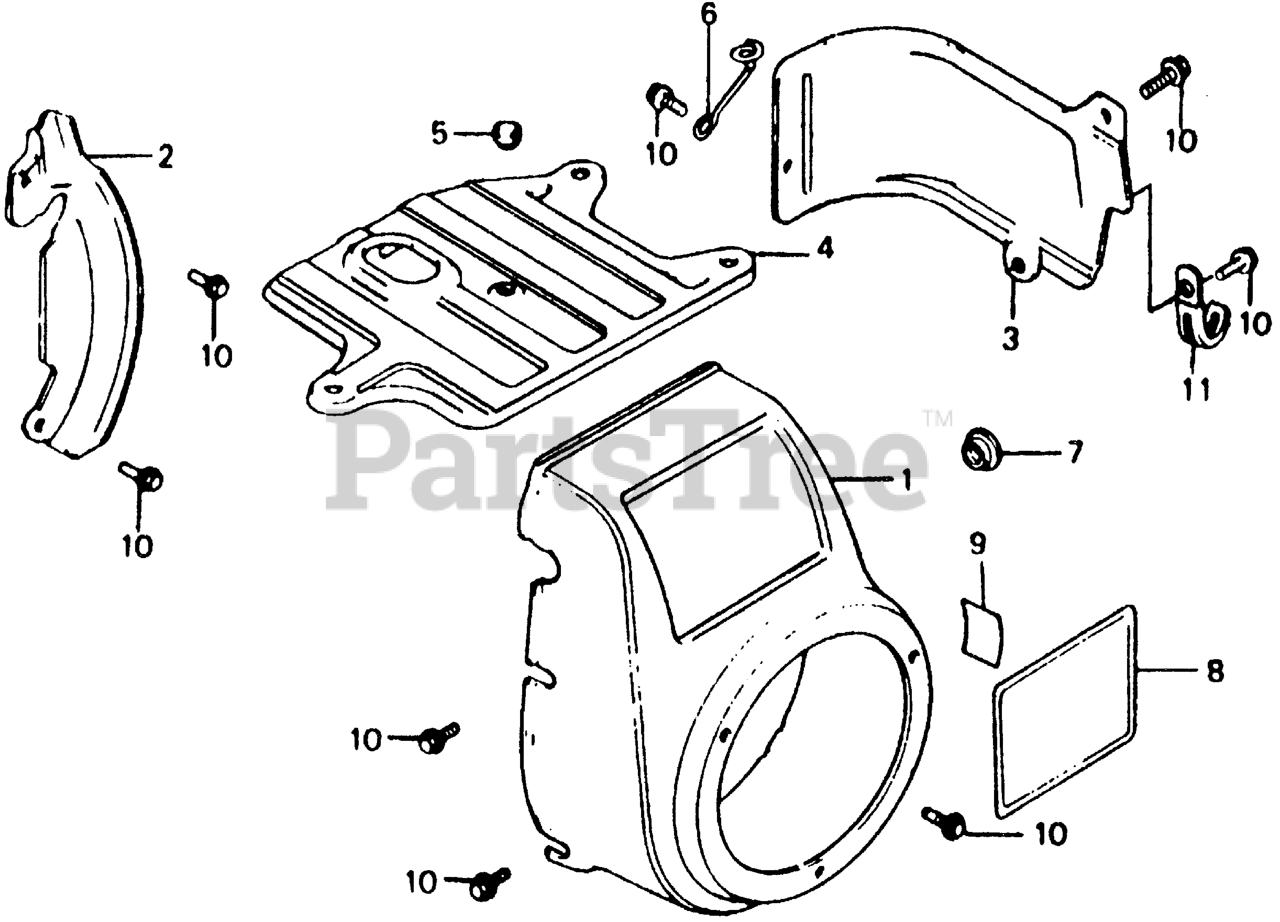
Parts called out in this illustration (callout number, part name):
1	COVER, FAN *R8* (BRIGHT RED)
2	PLATE, SIDE
3	SHROUD
4	COVER, TOP
5	GROMMET, TOP COVER
6	CLAMP, IGNITION TUBE
7	GROMMET, DRAIN HOLE
9	MARK, OIL CAUTION
10	BOLT, FLANGE (6X12) (CT200)
11	CLIP, CABLE
